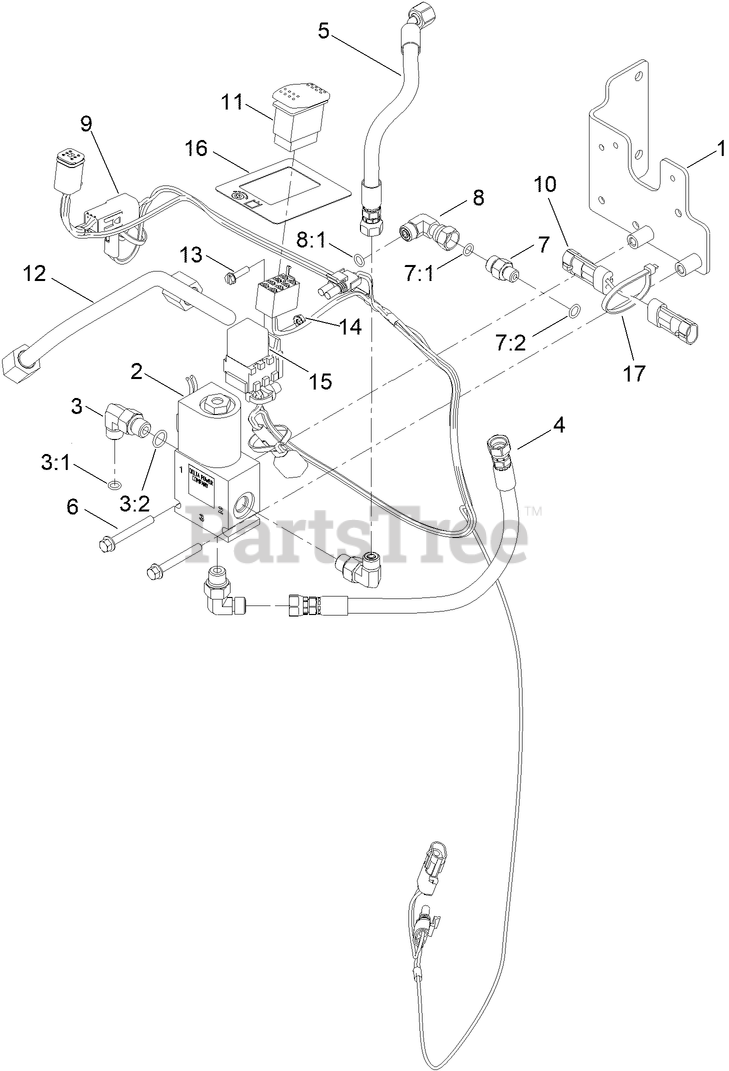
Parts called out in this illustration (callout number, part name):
2	SOLENOID VALVE
3	FITTING-ELBOW, 90 DEG
3:1	O-RING
3:2	O-RING
4	HOSE ASM
5	HOSE ASM
6	SCREW-HHF
7	FITTING-STRAIGHT
7:1	O-RING
7:2	O-RING
8	FITTING-ADAPTOR
8:1	O-RING
9	HARNESS-WIRE,TRACTION ENABLE
10	HARNESS-WIRE, TRACTION ENABLE JUMPER
11	SWITCH-INTERMITTENT
12	HYDRAULIC TUBE ASM
13	SCREW-HWH
14	NUT-KEPS
16	DECAL, TRACTION
17	TIE-CABLE
